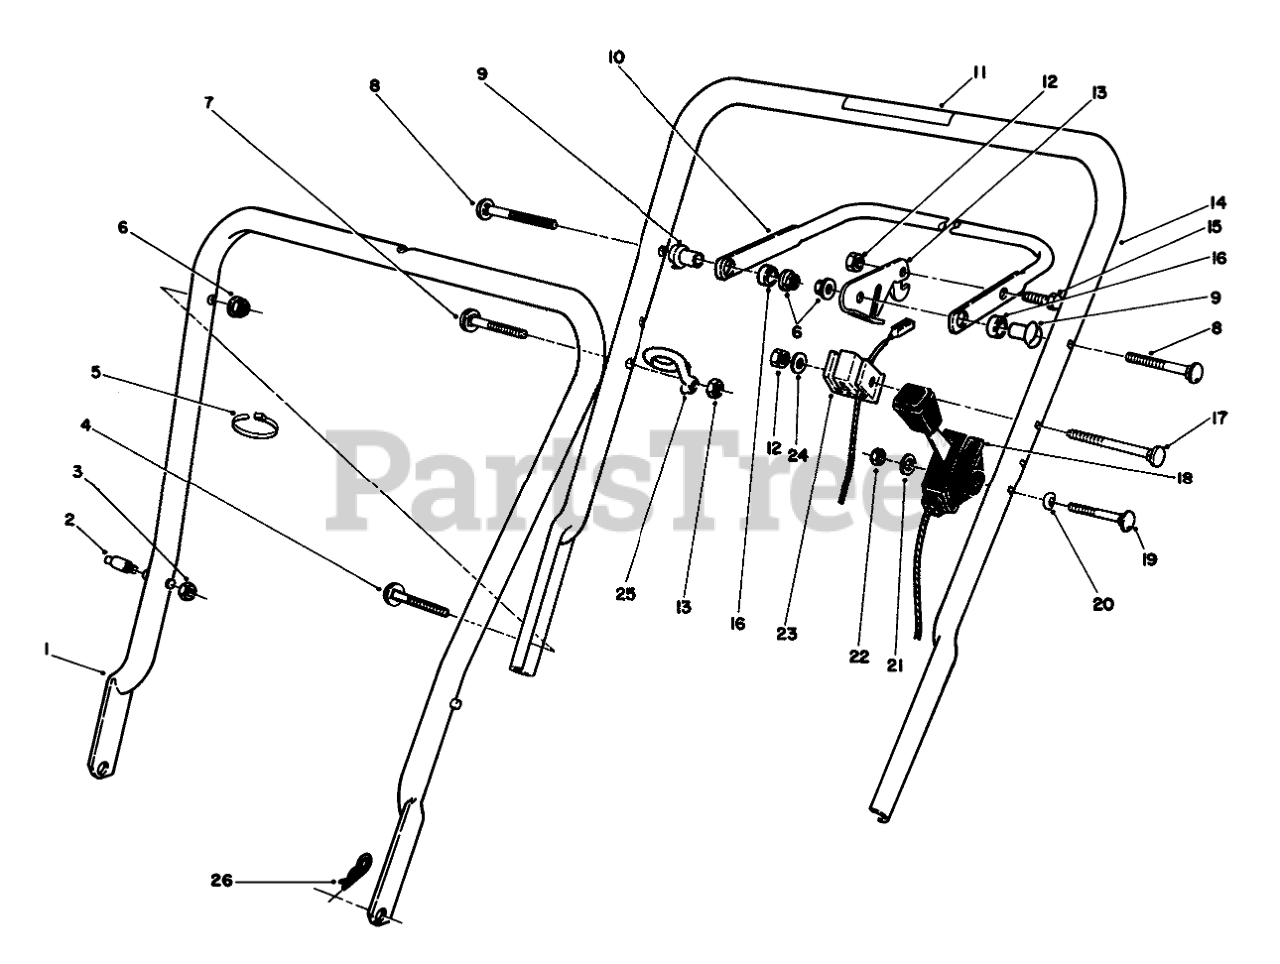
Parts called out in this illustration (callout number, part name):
1	LOWER HANDLE ASM
2	HANDLE PIN
3	NUT-LOCK, NI
4	SCREW
5	TIE-CABLE
6	NUT-LOCK, NI
7	HANDLE SCREW
8	5/16-18 X 2 HNDLE SCREW
9	SPACER-SUPPORT
10	Bar-Control
11	WARNING DECAL
12	NUT-LOCK, NI
13	LEVER-CONTROL
14	Handle-Upper (Incl. Ref. #11)
15	SCREW-HH
16	SPACER-NYLON
17	HANDLE SCREW
18	THROTTLE CONTROL - R&S
19	SCREW-SHH
20	Washer-Curved
21	WASHER-FLAT
22	NUT-LOCK, NI
23	SUPPORT-CABLE
24	WASHER-FLAT
25	Guide
26	PIN-COTTER, HAIR
